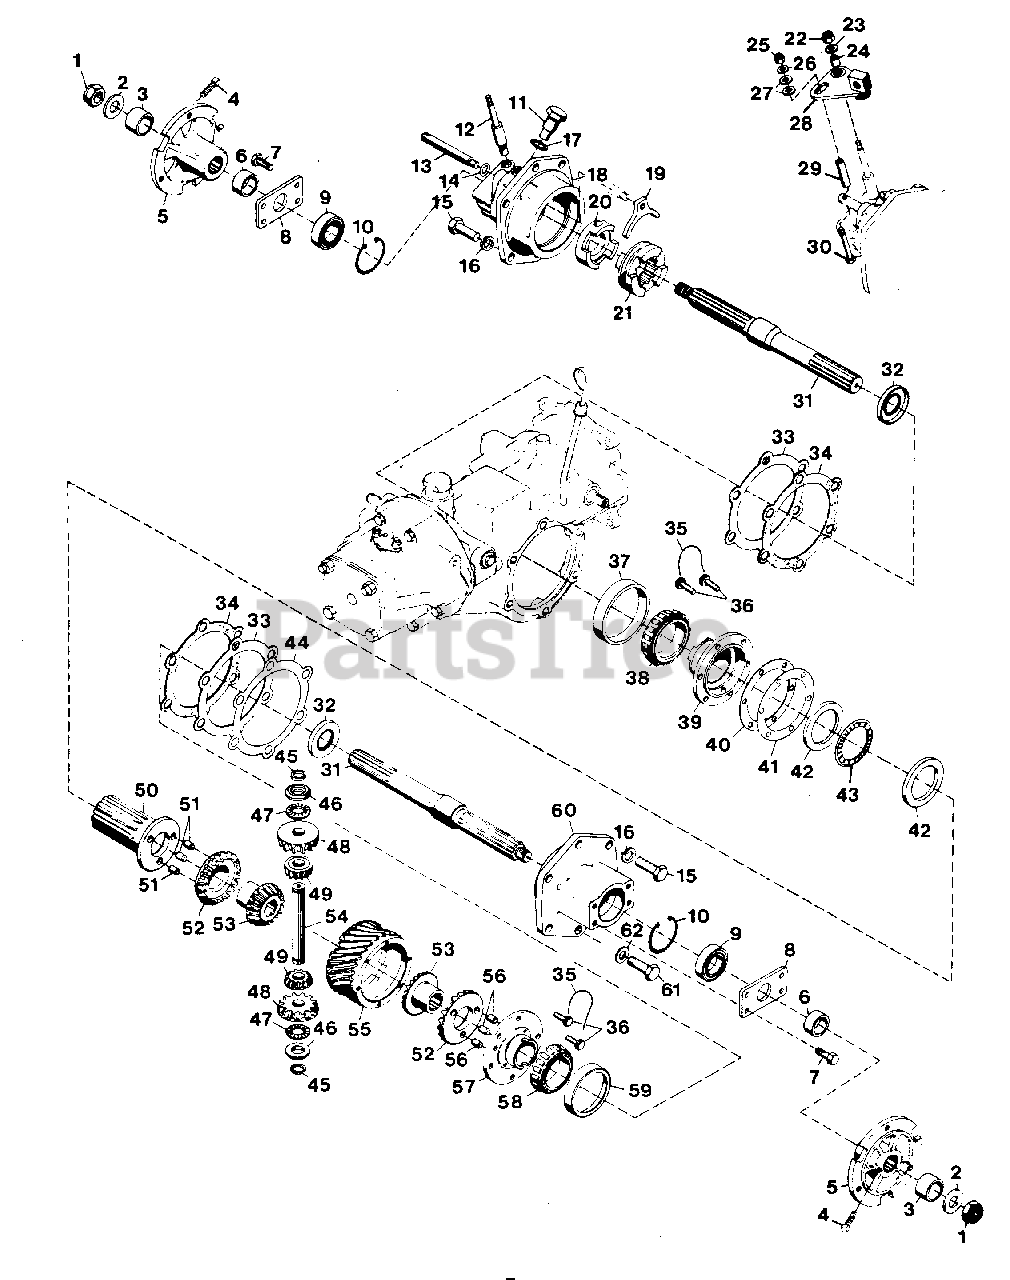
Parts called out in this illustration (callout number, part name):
1	NUT, HEX 3/4-10 LIGHT THIN
2	WASHER, FLAT .812X1.469X.134
3	SPACER
4	SCREW, SET 7/16-14X1.0 SQHCP
5	HUB, WHEEL
6	SPACER
7	BOLT, HEX 3/8-16X.750
8	PLATE, END
9	BRG, BALL 1.000X2.000X.562
10	RING, RETAINING 2.000 BORE
11	BOLT, STATIONARY CLUTCH
12	PIVOT, STATIONARY
13	PIN, CLUTCH SLIDING
14	O-RING .438X.625X.094
15	BOLT, HEX 1/2-13X1.00
16	WASHER, LOCK 1/2 REG.
17	WASHER, OIL STRAINER NUT
18	HOUSING, AXLE 2-SPEED
19	YOKE, SHIFTING
20	CLUTCH, STATIONARY
21	CLUTCH, SHIFTING
22	NUT, LOCK 5/16-18
23	WASHER, FLAT .344X.688X.065
24	BUSHING, NYLON .375X.503X.875
25	NUT, LOCK 1/4-20
26	WASHER, FLAT .281X.625X.065
27	WASHER, FLAT .406X.812X.065
28	WELDMENT, ARM SHIFTER
29	BUSHING
30	BOLT, 1/4-20X2.25 GR. 8 PHD
31	AXLE, STRAIGHT
32	SEAL, OIL 1.188X2.000X.250
33	SHIM, AXLE HOUSING .020
34	GASKET, AXLE HOUSING
35	WIRE, BOLT
36	BOLT, SPECIAL 5/16-18
37	CUP, ROLLER BEARING
38	CONE, ROLLER BEARING
39	HOUSING, CLUTCH
40	SHIM, WORM GEAR .020
41	SHIM, WORM GEAR .005
42	RACE, THRUST 2.00X2.740X.031
43	BRG, NEEDLE THRUST .060
44	SHIM, AXLE HOUSING .005
45	RING, RETAINING .750 SHAFT
46	SPACER, .765X1.245X.200
47	BRG, NEEDLE THST .752X1.24X.078
48	GEAR, DIFF. SHIFTING BEVEL
49	GEAR, SPIDER BEVEL
50	SHIFTER, SPLINED PINNED
51	PIN, DOWEL .375X.375
52	GEAR, PINNED BEVEL
53	GEAR, DIFFERENTIAL BEVEL
54	PIN, SPIDER
55	GEAR, WORM 8 START
55	GEAR, WORM 6 START
56	PIN, DOWEL .375X.500
57	HOUSING, PINNED
58	CONE, ROLLER BEARING
59	CUP, ROLLER BEARING
60	HOUSING, AXLE
61	BOLT, HEX 1/2-13X1 NYLON INS.
62	SEAL, OIL DRAIN
